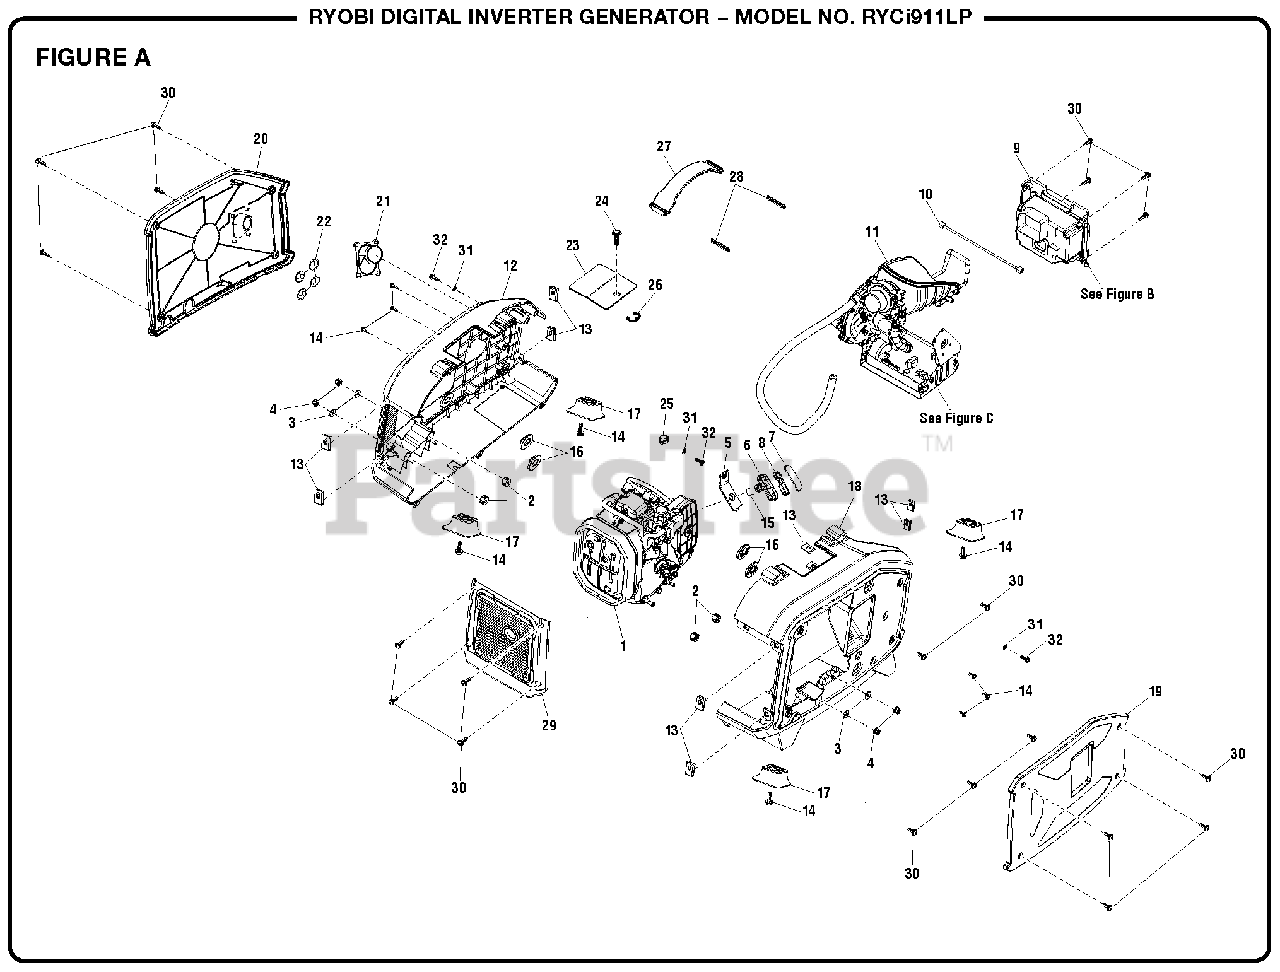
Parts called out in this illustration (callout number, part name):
1	Engine
2	Side Engine Isolator
3	Rubber Washer (ID6.25 x OD15.5 x 2t)
4	Lock Flange Nut (M6)
5	Starter Cover
6	Recoil Handle
7	Recoil Handle Cover
8	Recoil Handle Support
9	Control Panel Assembly
10	Stepper Motor Extended Wire Harness
11	Fuel System & Bracket Assembly
12	Panel Housing (Right)
14	Screw (M5 x 12 mm, T-25 Torx Washer Pan Hd.)
15	Rubber Grommet Handle
16	Rubber Grommet
17	Rubber Foot w/Metal Insert and Ribs
18	Panel Housing (Left)
19	Maintenance Panel (Left)
20	Maintenance Panel (Right)
21	Rubber Grommet
22	Internal Tooth Washer (ID5)
23	Spark Plug Door
24	Screw (M5 x 16 mm, T-25 Torx Washer Pan Hd.)
25	Fuel Hose Clamp
26	E-Clip Lock Washer
27	Rubber Handle (Upper)
28	Side Lock (U-Shaped)
29	Muffler Cover
30	Screw (M5 x 18 mm, T-25 Torx Washer Pan Hd.)
31	Washer (ID5.2 x OD10 x 1t)
32	Screw (M5 x 16 mm, T-25 Torx Pan Hd.)
